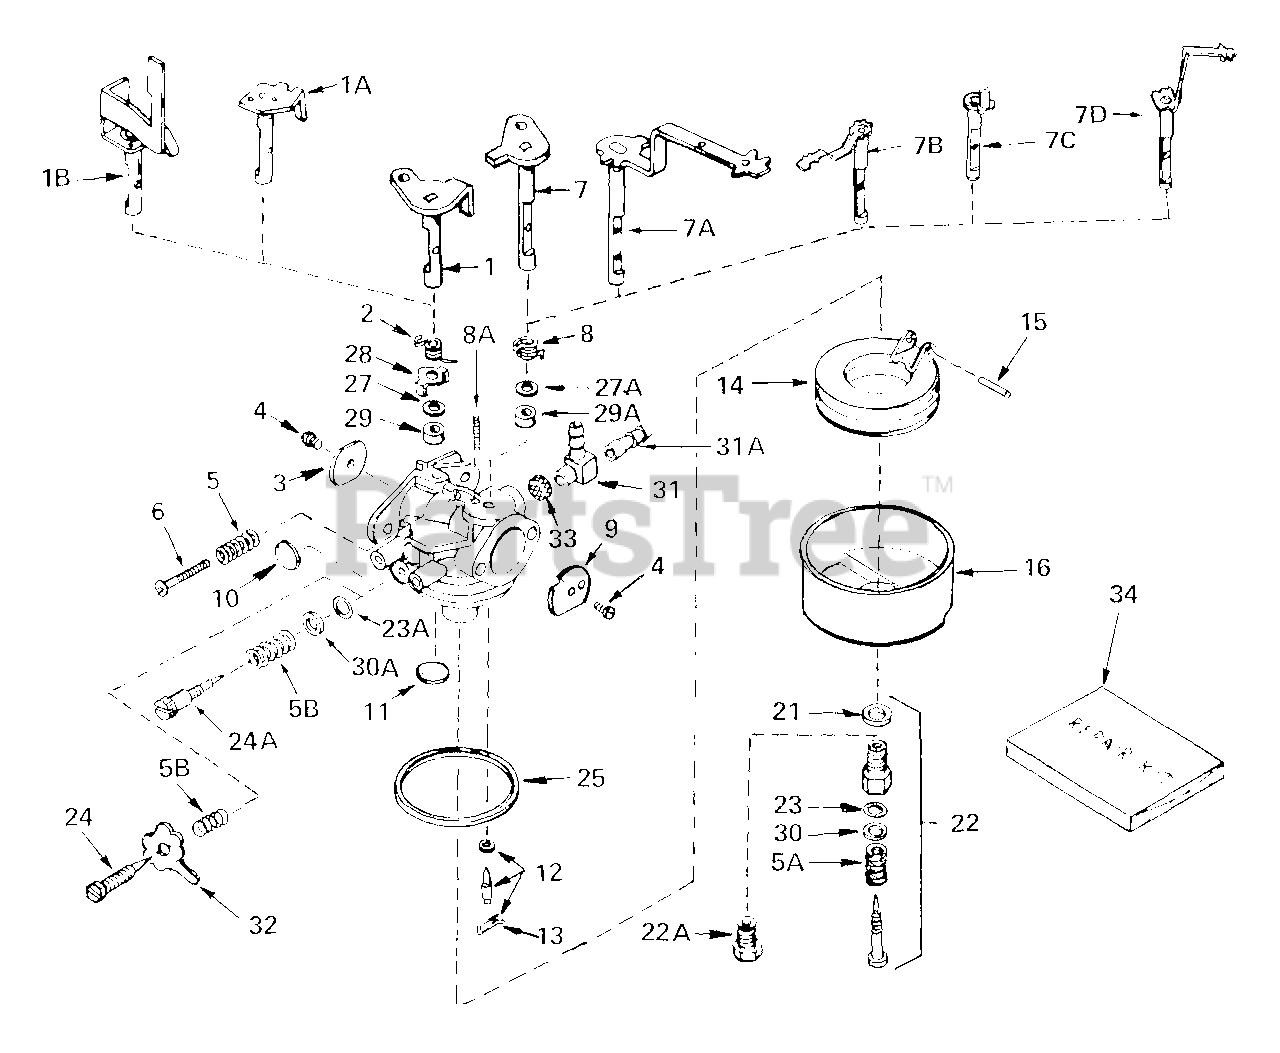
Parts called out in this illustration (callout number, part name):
1A	"Shaft & Lever Assy., Throttle
2	Spring, Throttle return
3	Shutter, Throttle
4	Screw, Throttle & Choke shutter
12	Inlet Needle, Seat & Clip Assy.
13	Clip, Inlet needle
14	Float, Carburetor
15	Shaft, Float
16	Bowl, Float
21	Gasket, Bowl-to-body
22A	Nut, Float bowl
25	Gasket, Bowl-to-body
28	Retainer, Seal
31	Fitting, Fuel
